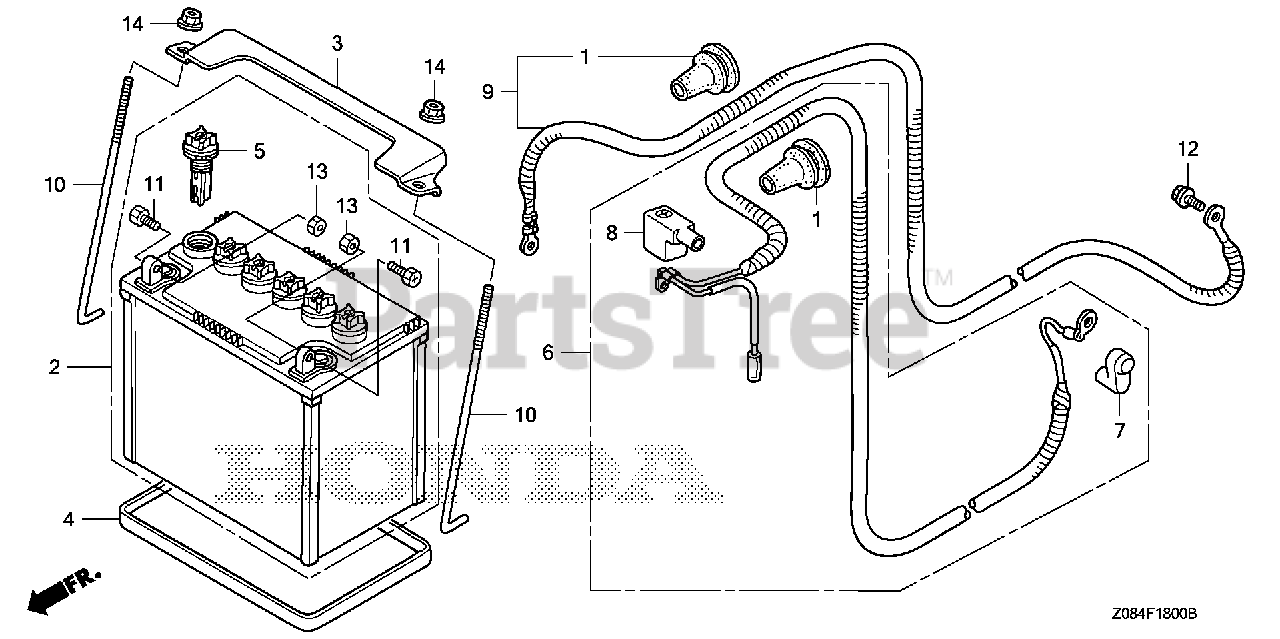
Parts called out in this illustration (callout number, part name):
1	GROMMET, MAIN WIRE
2	BATTERY (34A19L-MF)9L-MF) (YUASA) (MSDS)
3	PLATE, BATTERY SETTING
4	BOX, BATTERY
5	PLUG, VENT (YUASA)
6	CABLE ASSY., STARTER
7	COVER, STARTER TERMINAL
8	COVER A, BATTERY TERMINAL
9	CABLE ASSY., GROUND
10	BOLT, BATTERY SETTING
11	BOLT, BATTERY TERMINAL
12	BOLT, FLANGE (6X12)
13	NUT, BATTERY TERMINAL
14	NUT, FLANGE (6MM)
